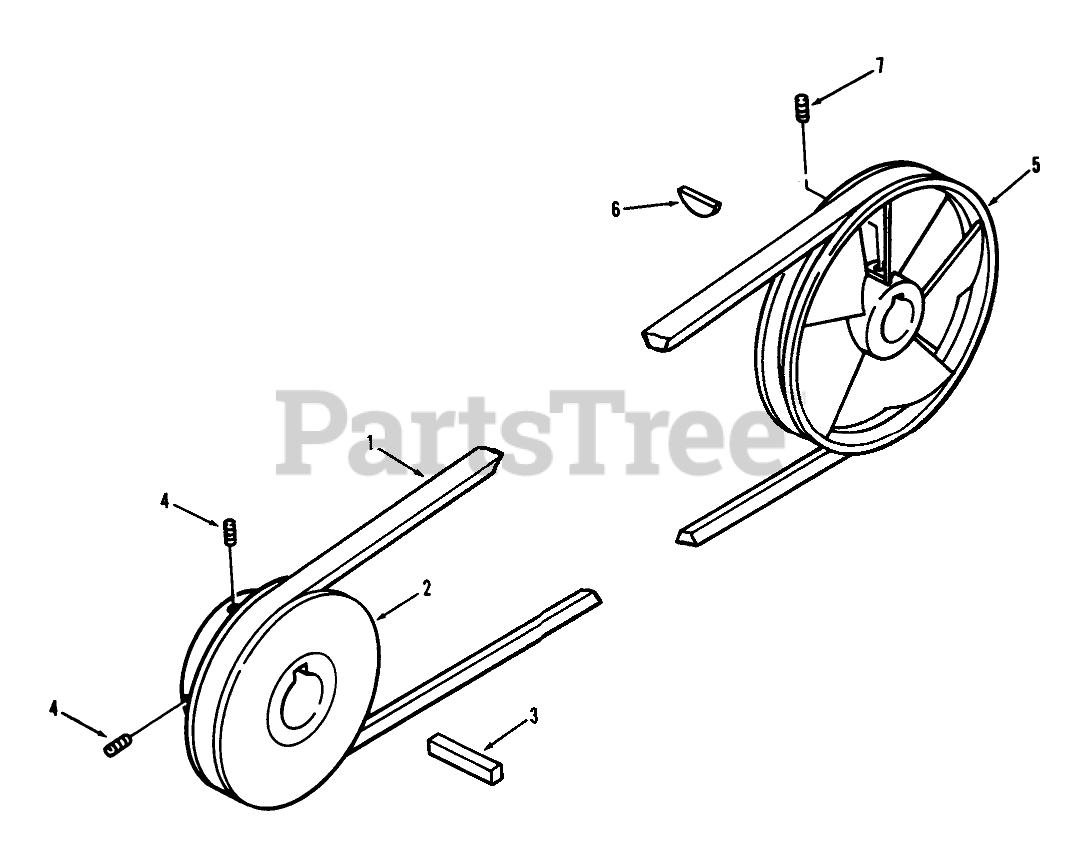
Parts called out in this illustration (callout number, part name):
1	V BELT
2	PULLEY
4	Set Screw
5	Pulley Trans
6	KEY-HI PRO
7	Set Screw
